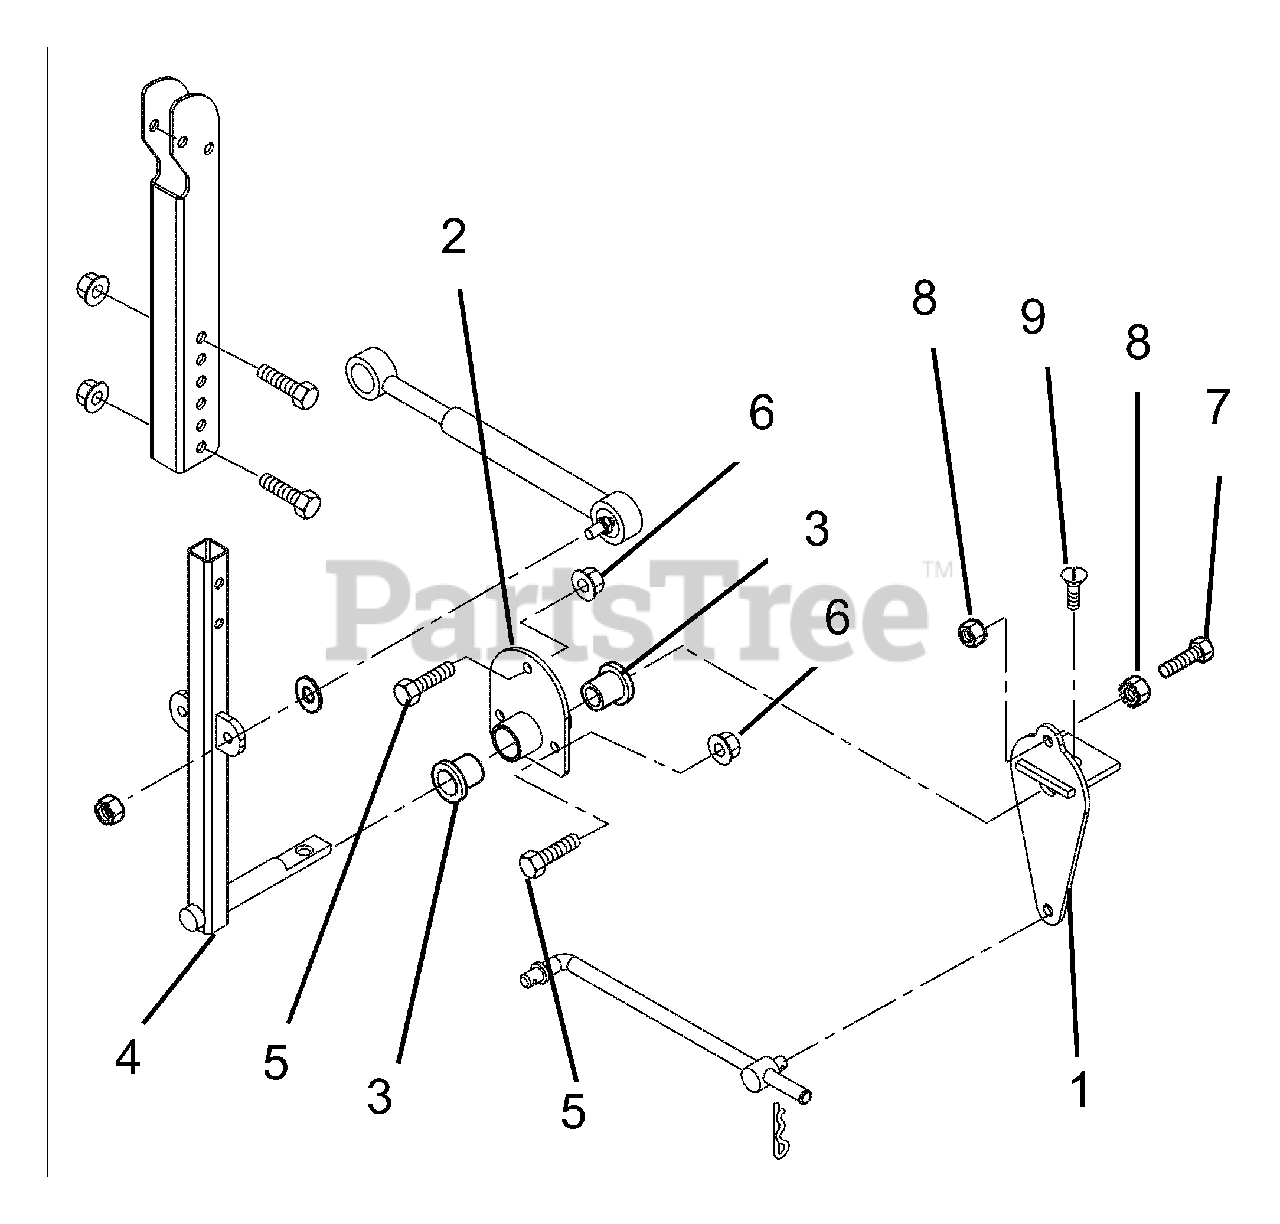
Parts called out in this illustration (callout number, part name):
1	WMT, CONTROL LINK
2	WMT, STEERING BUSHING
3	BUSHING-1"X.75"X1"
4	WMT, CONTROL ARM
5	@BLT-HEX .31-18X.75 GR5 YWZC
6	@NUT-LK-NYL-FLG .31-18 YWZC
7	BLT-HEX .38-16X3.00 GR5 FTH YZ
8	@NUT-SPNLK-FLG .375-16 YWZC
9	BOLT, 3/8-16X1 FSHCS PLN
